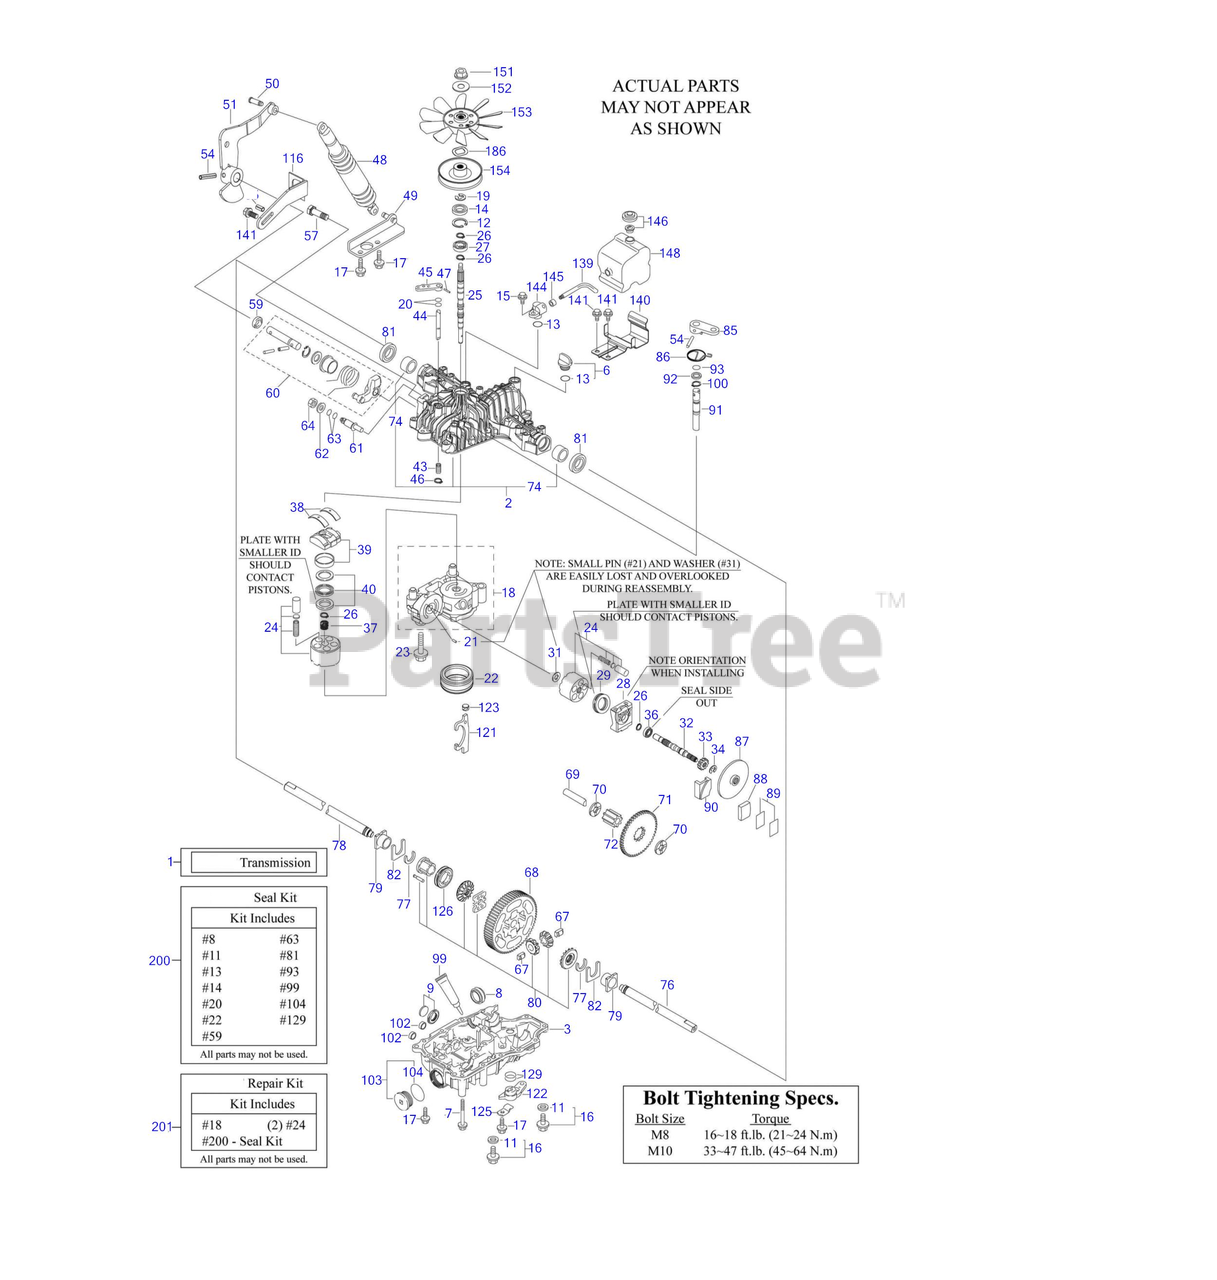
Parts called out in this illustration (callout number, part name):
1	K62AF TRANSAXLE
2	UPPER CASE KIT
7	M8 x 75 SCREW CAP
11	WASHER SEAL 10
12	SNAP RING C 35
15	M8 x 20 FLANGE BOLT
16	DRAIN BOLT KIT
17	TAPPING SCREW 8 x 30
20	0-RING 1A P10A
23	M10 x 65 BOLT
24	CYLINDER BLOCK KIT(MOTOR
26	SNAP RING S15
27	BEARING
28	MOTOR HOUSING
29	THRUST BEARING
36	BEARING 6302DUC3
39	SWASH PLATE ASSEMBLY
40	THRUST BEARING KIT
47	SPRING PIN 3.0A x 20
48	SHOCK ABSORBER K65
51	CONTROL LEVER
54	ROLL PIN 6 x 40
57	BOLT M10 x 1.5
59	SEAL TC 162606
60	CONTROL SHAFT KIT
63	O-RING 1A P14
67	DIFFERENTIAL PINION PIN
69	FINAL PINION SHAFT
71	REDUCTION GEAR
72	FINAL PINION Gear
76	AXLE SHAFT LEFT
77	RETAINING RING 23
78	AXLE SHAFT RIGHT
80	DIFFERENTIAL LOCK KIT
82	THRUST WASHER
86	BRAKE RETURN SPRING
90	BRAKE ACTUATOR
92	WASHER 16 * 23 * 1.6
93	O-RING 1A P12
102	FLANGE PLUG 20
121	DIFFERENTIAL LOCK FORK
122	DIFFERENTIAL LOCK LEVER
126	DIFFERENTIAL LOCK SLIDER
129	0-RING 1A G25
141	TAPPING SCREW 8 * 20
146	VENT VALVE 15
148	RESERVOIR TANK
152	WASHER 11 * 31 * 32
200	SEAL KIT K62A
201	REPAIR KIT K62A
